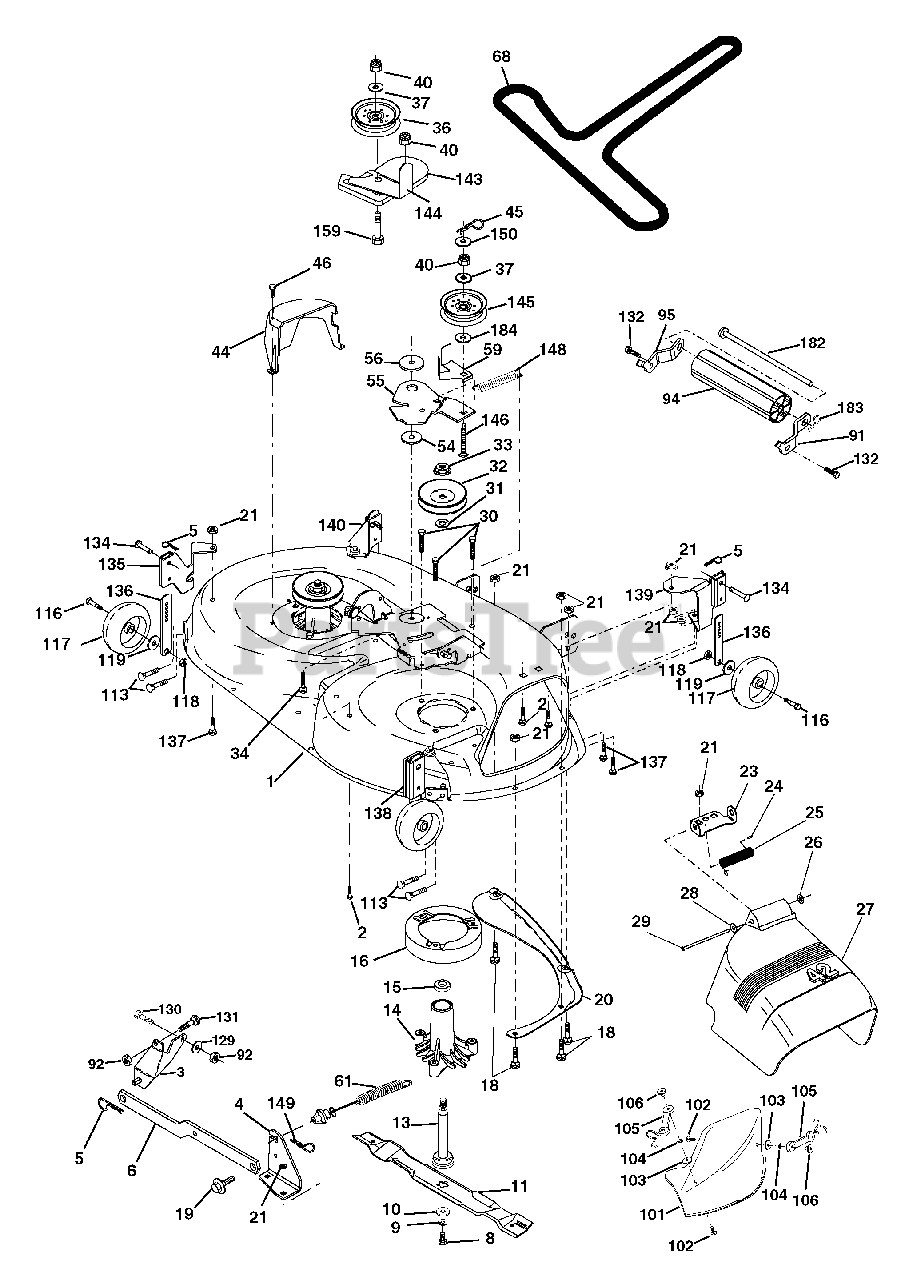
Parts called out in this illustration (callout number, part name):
1	Mower Deck Assembly, 42"
2	Bolt
3	Bracket Assembly,Sway Bar, Front
4	Bracket Sway Bar 42" Deck
5	Retainer Spring
6	Bar Sway Deck
8	Bolt, Hex 3/8-24 x 1.25 Gr. 8
9	Washer, Lock
10	Washer, Hardened
11	Blade Mower 42 High Perf.
11	Blade, Mulching
13	Shaft Assembly, Mandrel, Vented
14	Housing, Mandrel, Vented
15	Bearing, Ball, Mandrel
18	Bolt, Carriage 5/16-18 x 5/8
19	Bolt, Shoulder
20	Baffle, Vortex
21	Nut Crownlock 5/16-18 UNC
22	Stiffener Bracket
23	Bracket, Deflector
24	Cap, Sleeve
25	Spring, Torsion, Deflector
27	Shield, Deflector
28	Washer 11/32 x 5/8 x 16 Ga.
29	Rod, Hinge
30	Screw Thdrol Hex
31	Washer, Spacer
32	Pulley, Mandrel
33	Nut, Toplock, Flanged
36	Pulley, Idler, Flat
37	Washer 13/32 x 13/16 x 16 Gauge
40	Nut Crownlock 3/8-16 UNC
44	Guard, Mandrel, L.H.
45	Retainer
46	Screw, Thd. Roll 1/4-20 x 5/8
54	Washer, Hardened
55	Arm, Idler
56	Spacer, Retainer
59	Guard, TUV Idler
61	Spring Ext Elect Clutch 42" Dck
91	Bracket Asm Noseroller Lh
92	Nut Lock Hex 5/16-18
94	Roller Nose 38-50
95	Bracket Asm Noseroller Rh
101	Mulcher Cover
102	Screw
103	Washer #10
104	Washer, Lock
105	Latch Assembly, Bagger
106	Nut, Weld
113	Screw 5/16-18 x 3/4 Tap R
116	Bolt, Shoulder
117	Wheel, Gauge
118	Nut, Centerlock 3/8-16
119	Washer 3/8 x 7/8 x 14 Gauge
129	Washer 13/32 x 13/16 x Ga.
130	Bolt Fin Hex 3/8-16unc x 1 Gr.5
131	Bolt Rdhd Sqnk 3/8-16unc x 1
132	Screw 3/8-16 x .75
134	Pin Head Rivet
135	Bracket Asm Whl GA R LH
136	Bar Adjusting GA WHL
137	Bolt Carr 5/16-18 x 5/8
138	Bracket Asm Whl GA R RH
139	Bracket Asm Whl GA F RH
140	Bracket Asm Whl GA F LH
143	Bracket Arm Idler 42"
144	Keeper Belt 42" Clutch Cable
145	Pulley Idler Flat
146	Bolt Carriage Idler
148	Spring Return Idler
149	Retainer Spring Yellow Zinc
150	Washer 9/32 x 3/4 x 16 Ga.
159	Bolt Rdhd Sqn 3/8-16 UNC x 1- 3/4
182	Rod Roller Nose
183	Retainer Spring
